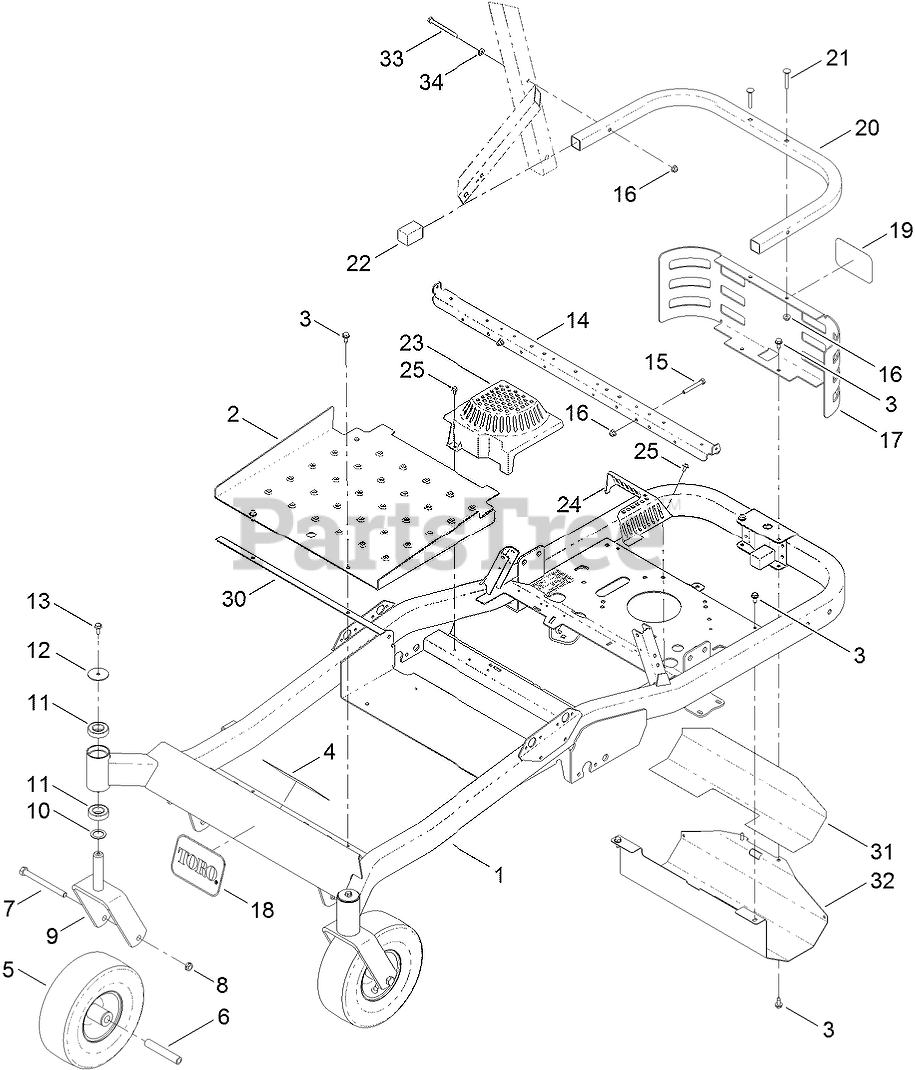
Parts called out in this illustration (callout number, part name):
2	PAN-FLOOR
3	SCREW-HWHTF
4	DECAL-SAFETY
5	TIRE and Wheel ASM (Kenda)
6	BUSHING-SPANNER
7	SCREW-HH
8	NUT-LOCK, NI
9	CASTER FORK ASM
10	WASHER-THRUST
11	BEARING-BALL
12	WASHER
13	SCREW-HHF
14	SUPPORT-SEAT
15	SCREW-HH
16	NUT-HF, NI
17	GUARD-REAR
18	DECAL
20	TUBE-GUARD
21	Screw-CARR
23	COVER-FAN, RH
24	COVER-FAN, LH
25	SCREW-HHFTF
30	STRIP-VIBRATION, ANTI
31	FOIL-HEAT SHIELD
32	GUARD-MUFFLER
33	SCREW-HH
34	WASHER-PLAIN
